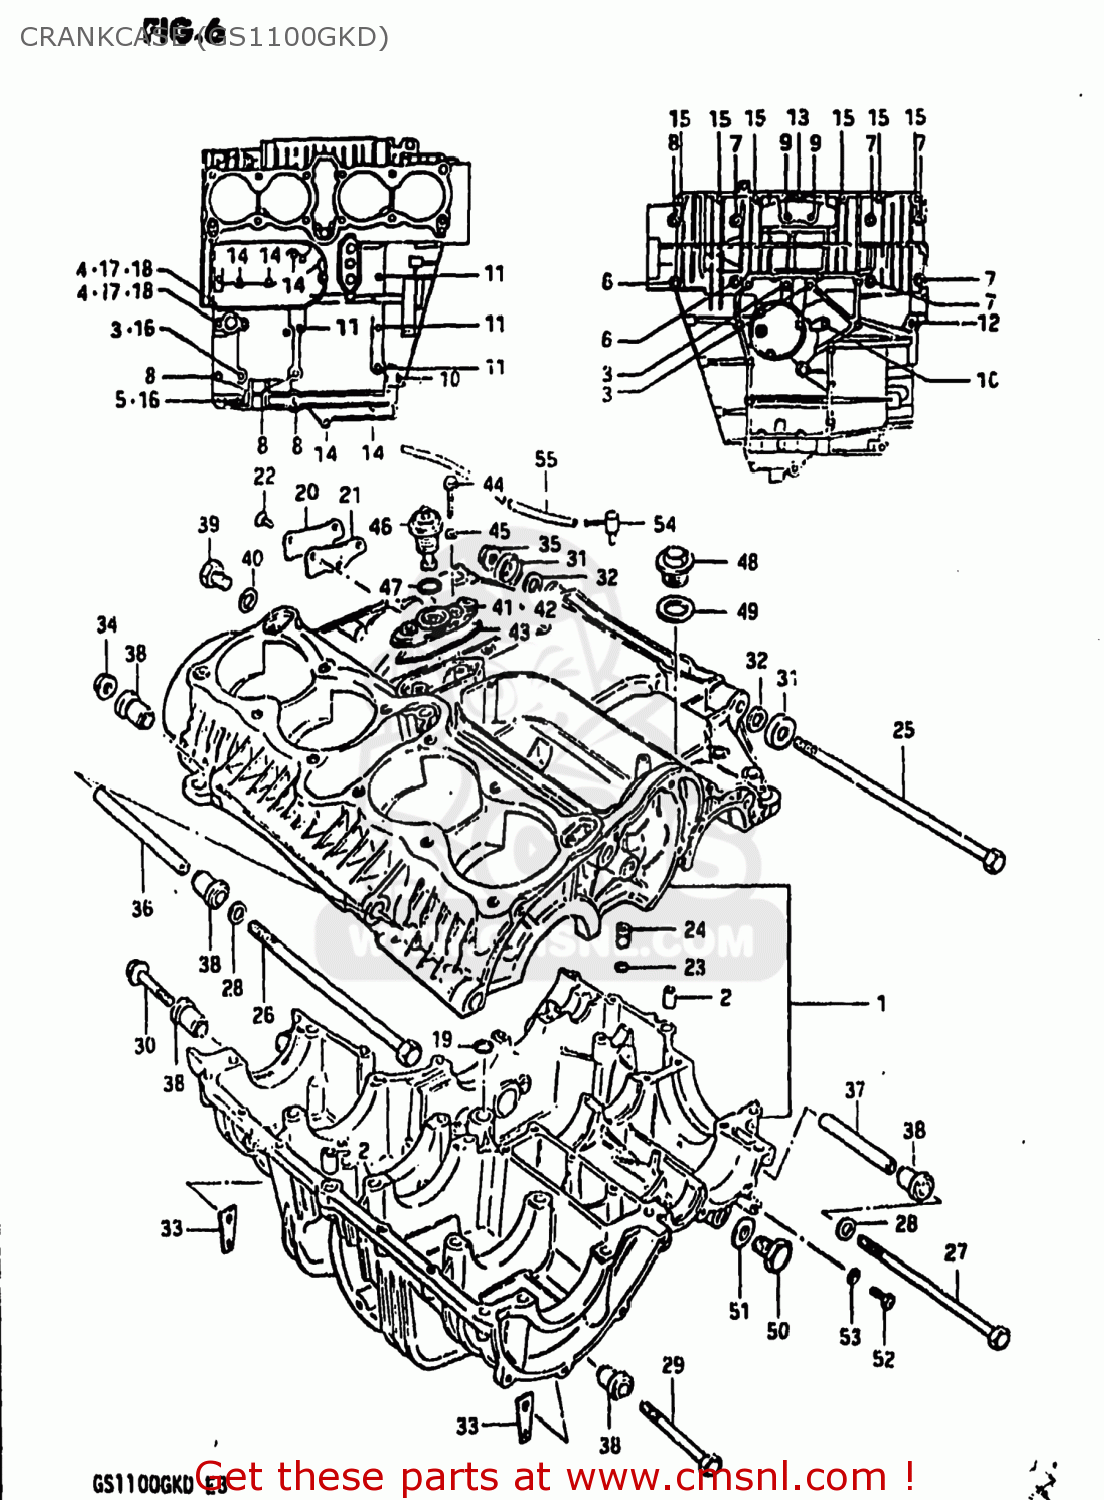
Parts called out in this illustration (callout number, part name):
1	CRANKCASE ASSEMBLY
2	PIN
3	BOLT
4	BOLT 8X110
5	BOLT
6	BOLT
7	BOLT (8X90)
8	BOLT (8X65)
9	BOLT 8X60
10	BOLT (6X90)
11	BOLT (6X75)
12	BOLT 6X55
13	BOLT 6X50
14	BOLT (6X45)
15	BOLT
16	NUT 8MM
17	NUT
18	GASKET 8.2X14X1 (NAS)
19	O RING(D:3.2,ID:12.9)
20	CAP,OIL GALLERY
21	GASKET,OIL GALLERY (MCA)
22	SCREW
23	O RING(D:1.05,ID:3.1)
24	UNION
25	BOLT
26	BOLT 10X250
27	BOLT
28	WASHER
29	BOLT
30	BOLT 10X55
31	WASHER
32	WASHER(10.5X20X3.2)
33	NUT
34	NUT
35	NUT 10MM
36	SPACER
37	SPACER
38	BUSH
39	PLUG (14X12)
40	GASKET(14X19.2X2) (NAS)
41	HOUSING,OIL PRESSURE SWITCH
42	HOUSING,OIL PRESSURE SWITCH
43	O RING,PRESSURE SWITCH HOUSING
44	BOLT
45	WASHER
46	SWITCH ASSEMBLY
47	O RING(D:1.9,ID:18.8)
48	PLUG
49	GASKET
50	PLUG
51	GASKET(14X19.2X2) (NAS)
52	SCREW(6X10)
53	WASHER
54	BPLUG,BEVEL GEAR BREATHER
55	HOSE
